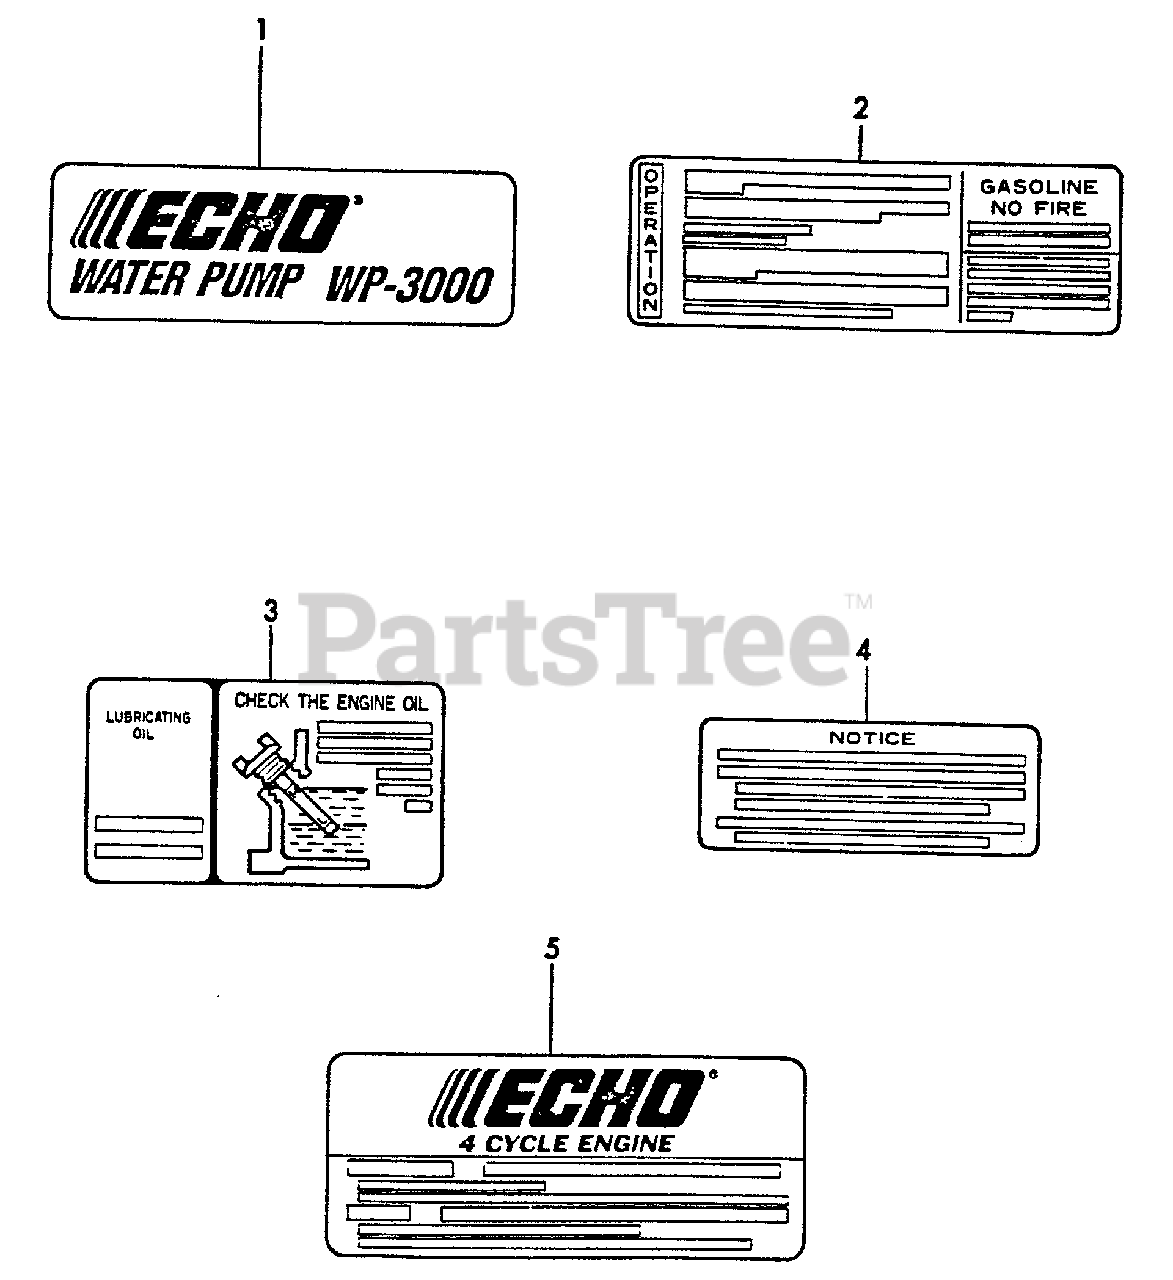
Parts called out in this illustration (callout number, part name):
1	LABEL - MODEL WP3000
2	LABEL, OPERATION
3	LABEL, OIL
4	LABEL - AIR FILTER
5	LABEL - ECHO
